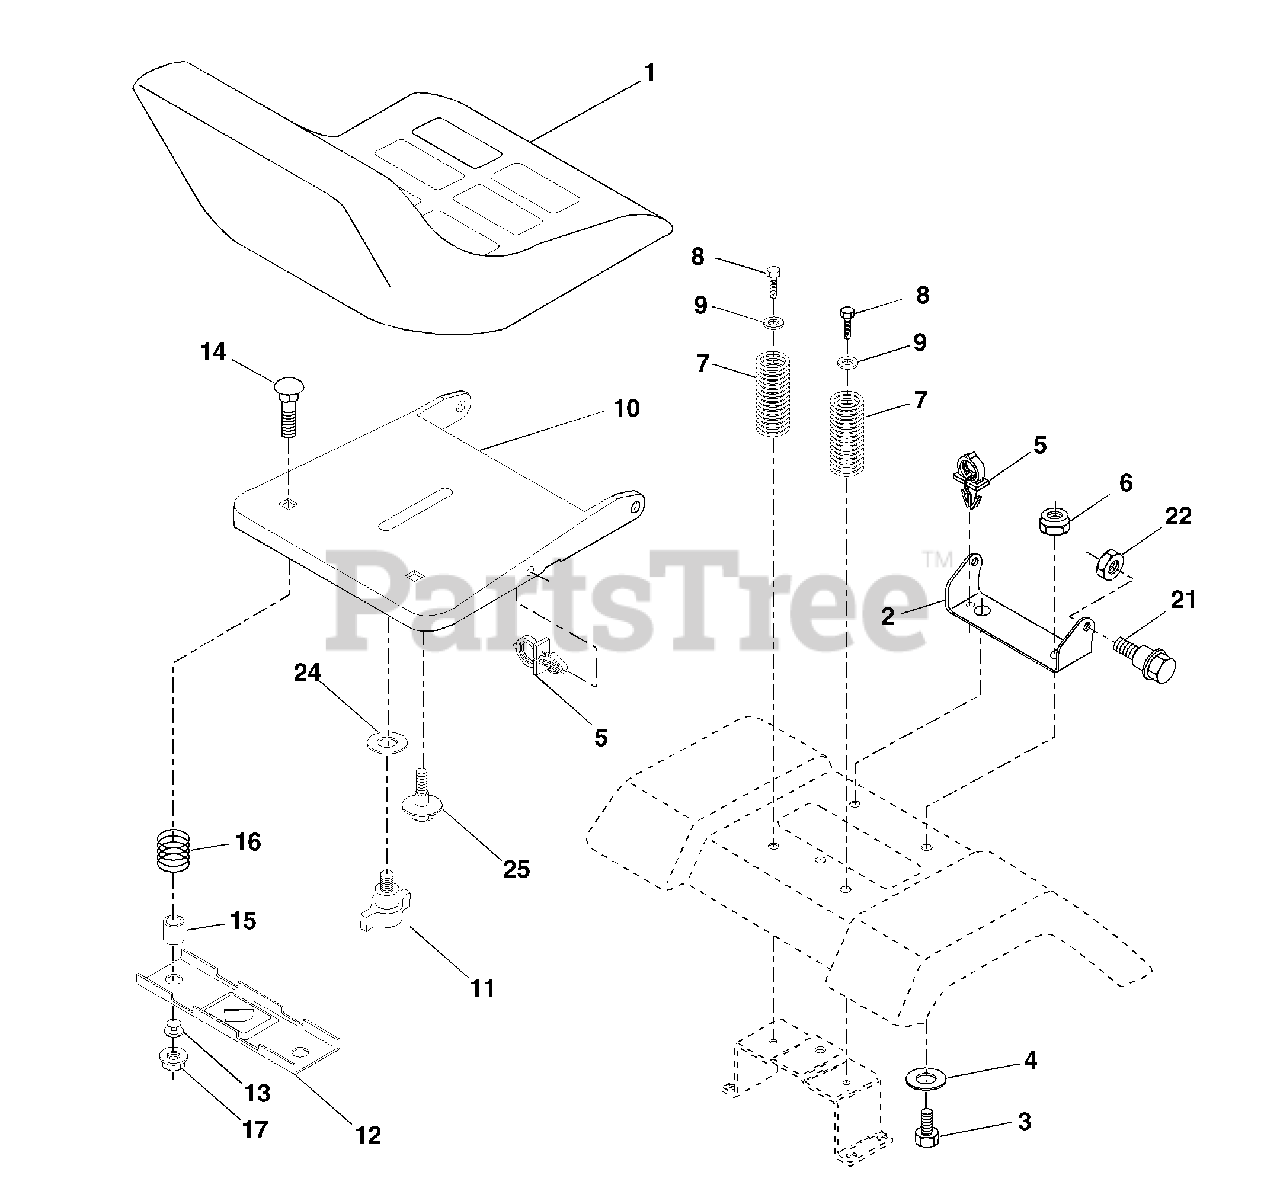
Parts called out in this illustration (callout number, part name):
1	Seat
2	Bracket Pivot Seat 8 720
3	Bolt Fin Hex 3/8-16unc X 1
4	Washer 13/32 X 1 X 10 Ga
5	Clip Push-In
6	Nut Hex w/Ins. 3/8-16 Unc
7	Spring Seat Cprsn 2 250 Blk Zi
8	Screw 3/8-16 x 1.5 Smgml
9	Washer 13/32 X 1 X 14 Ga.
10	Pan Seat
11	Knob Seat
12	Bracket Mounting Switch
13	Bushing Snap Blk Nyl 50 Id
14	Bolt Rdhd Sqnk 1/4-20x1-1/2
15	Spacer Split 28x 88
16	Spring Cprsn
17	Nut Lock 1/4 Lge Flg Gr 5 Zinc
21	Bolt Shoulder 5/16-18 Unc
22	Nut Hex Lock W/Ins 5/16-18
24	Washer 17/32 X 1-3/16 X 12 Ga.
25	Bolt Shoulder 5/16-18 X 62
